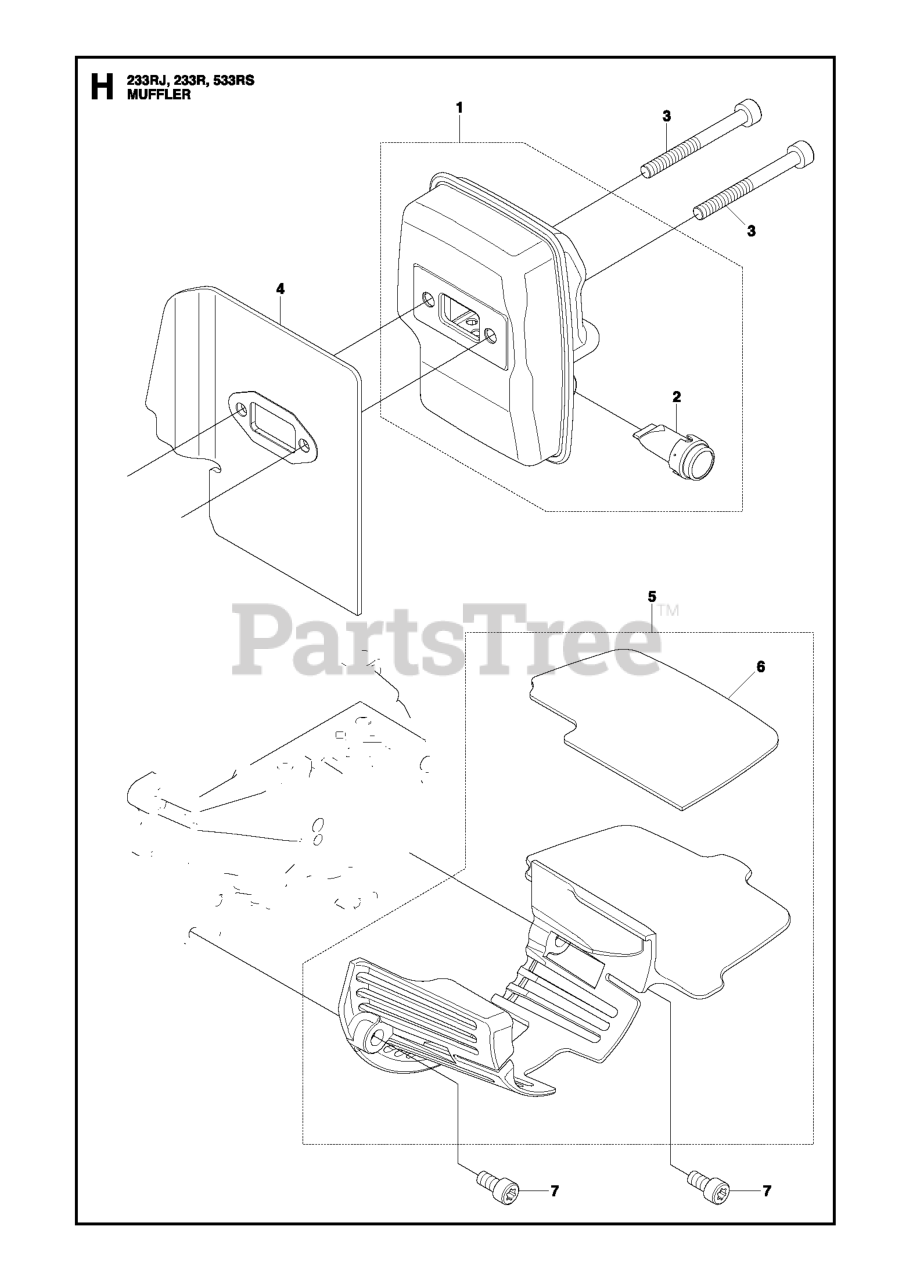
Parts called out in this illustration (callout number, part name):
1	MUFFLER
2	ARRESTER
7	BOLT 08
